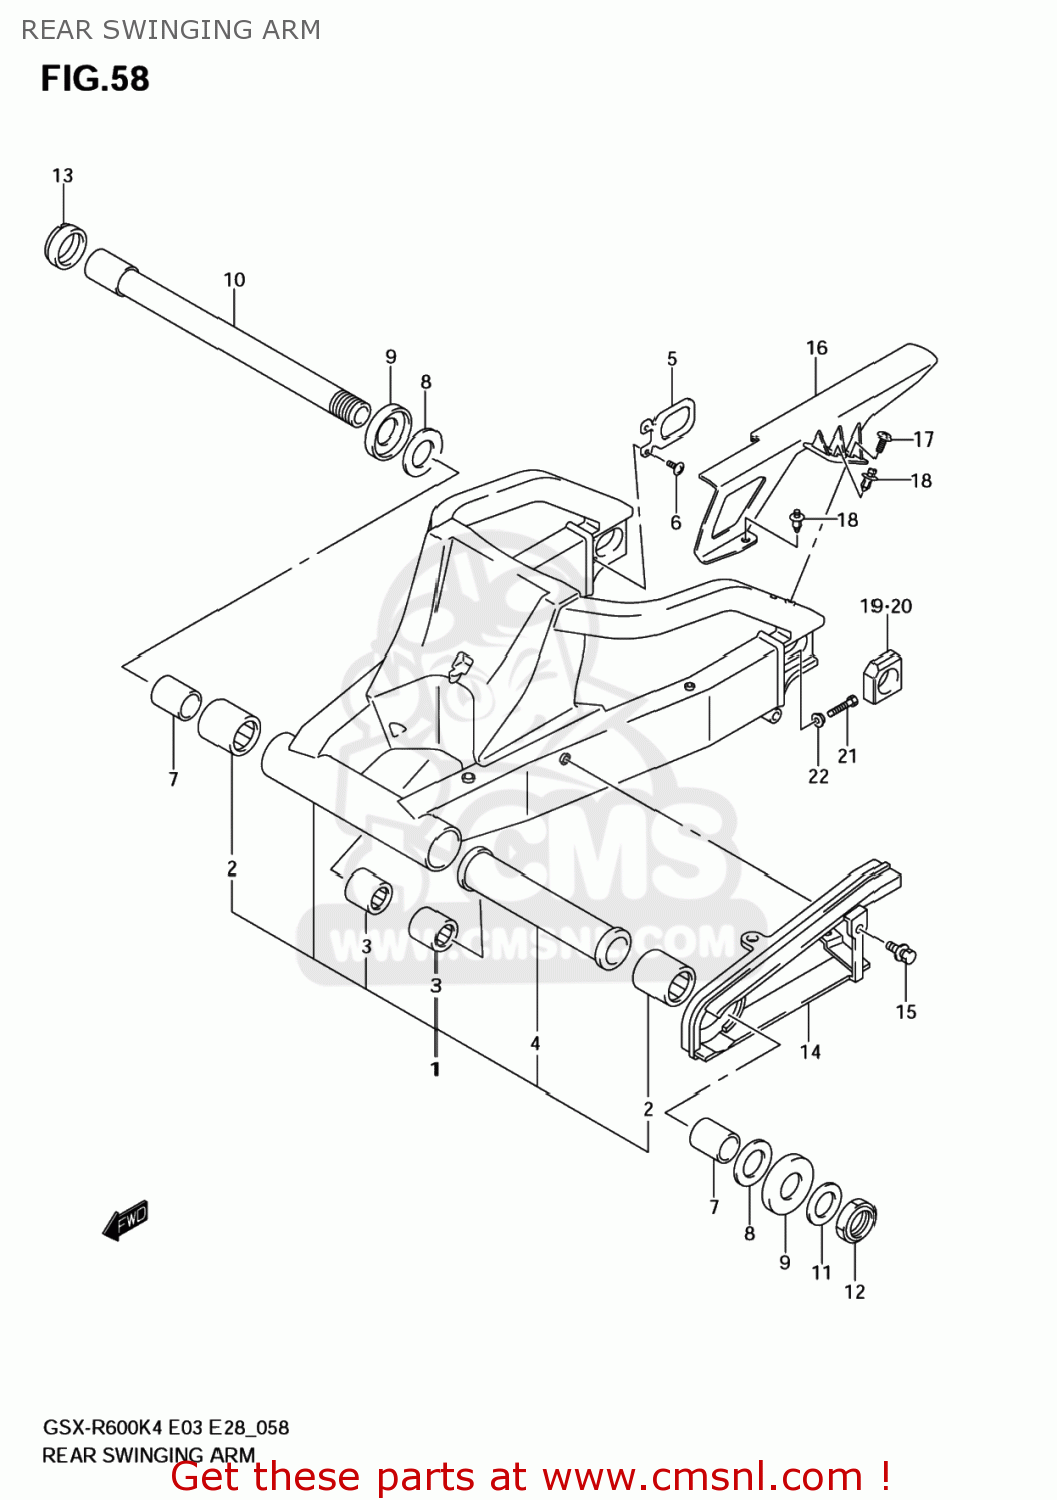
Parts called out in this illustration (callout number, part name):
1	SWINGINGARM ASSY,RR
2	BEARING(30X40X25)
3	BEARING(17X24X20)
4	SPACER,RR SWGARM PIVOT CTR
5	PLATE,RR SWING ARM BRKT
6	SCREW(6X16)
7	SPACER,REAR SWING ARM PIVOT
8	WASHER
9	DUST SEAL,RR SWGARM PIVOT
10	SHAFT,RR SWINGINGARM PIVOT
11	WASHER(25.2X42X3.2)
12	NUT
13	NUT,RR SWGARM PIVOT BOLT
14	BUFFER,CHAIN TOUCH DEFENSE
15	BOLT(6X17.8)
16	CASE,CHAIN
17	SCREW(6X16)
18	CLIP(BLACK)
19	ADJUSTER,CHAIN,R
20	ADJUSTER,CHAIN
21	BOLT(8X50)
22	NUT
